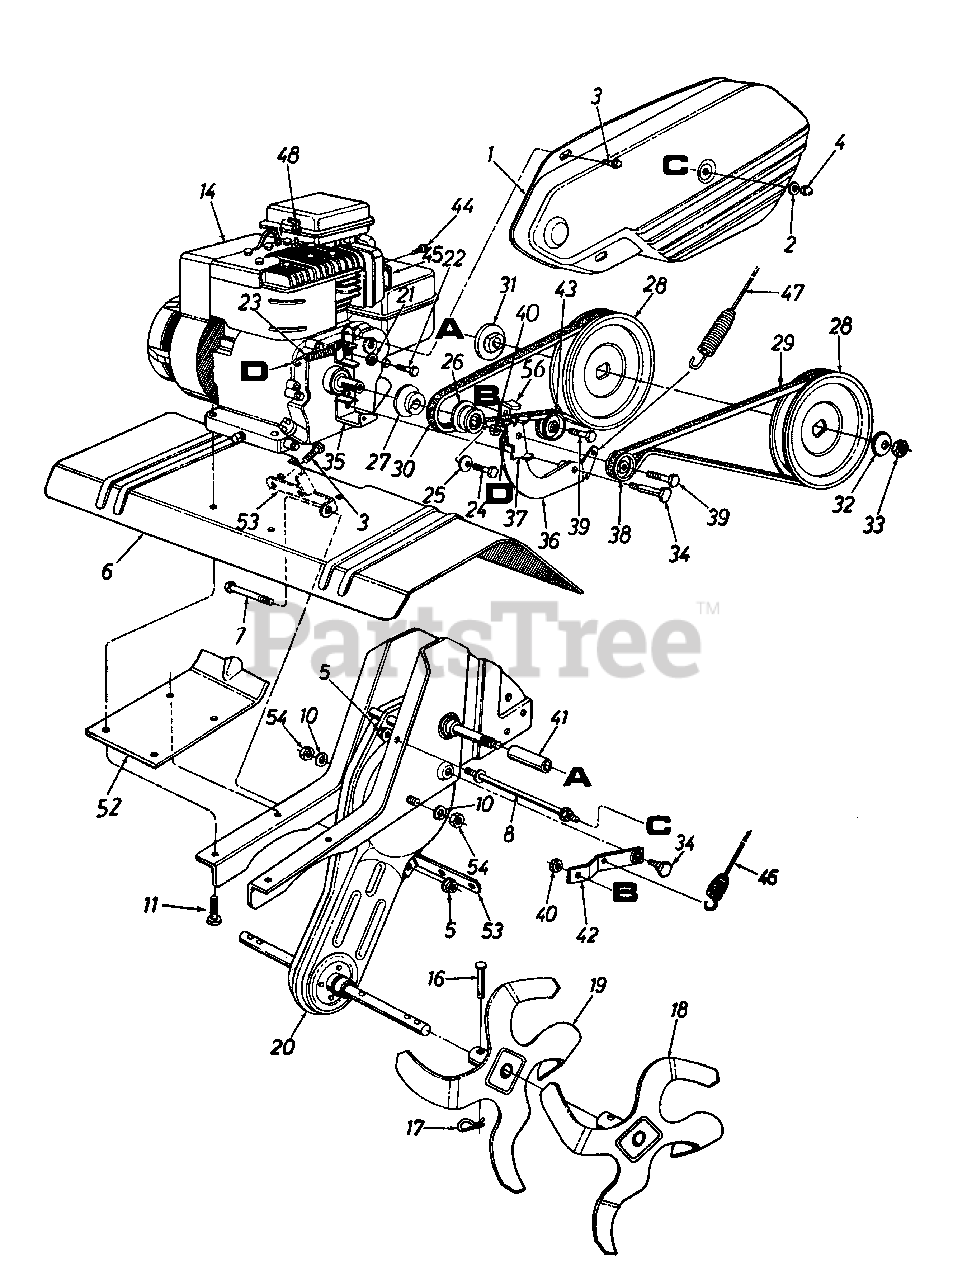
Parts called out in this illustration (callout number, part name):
2	Fl-Wash. .266" I.D. x .625" O.D.
3	Hex Wash. Hd. TT-Tap Scr. 1/4-20 x .5" Lg.
4	Hex L-Stop Nut 1/4-28 Thd.
5	Hex Flange Top L-Nut 5/16-18 Thd. (Gr. 5)
8	Belt Cover Bolt
10	L-Wash. 7/16" I.D.
11	Hex L-Wash. TT-Tap Scr. 3/8-16 x 1.25" Lg.
14	Engine
16	Clevis Pin .375" Dia. x 1.62" Lg.
17	Internal Cotter Pin
20	Chain Case Ass'y. Comp.
21	L-Wash. 5/16" I.D.
22	Hex Bolt 5/16-24 x .5" Lg.
23	Return Spring 2.7" Lg.
24	Hex Bolt 3/8-24 x 1.25" Lg.
25	Bell-Wash. .396" I.D. x 1.14" O.D.
26	Outer Engine Pulley Half
27	Inner Engine Pulley Half
28	Fl-Pulley 6" Dia.
29	"V"-Belt (Reverse)
30	"V"-Belt (Forward)
31	Pulley Mounting Adapter
32	Bell-Wash. .535" I.D. x 1.5" O.D.
33	Hex Jam Nut 1/2-20 Thd. (Gr. 5)
34	Shld. Bolt 5/16-18 Thd.
35	Reverse Mounting Brkt.
36	Reverse Arm Ass'y.
38	Fl-Idler 2.12" O.D.
39	Hex Cap Bolt 3/8-16 x 1.25" Lg.
40	Hex Cent. Jam Nut 3/8-16 Thd.
41	Spacer .64" I.D. x 2.4" Lg.
43	Fl-Idler 2.12" O.D.
44	Hex Self-Tap Scr. #8-32 x .38" Lg.
45	Muffler Deflector
46	Clutch Control Cable-Forward
47	Clutch Control Cable-Reverse
48	Spark Plug Boot
54	Hex Nut 7/16-20 Thd.
56	Belt Keeper
